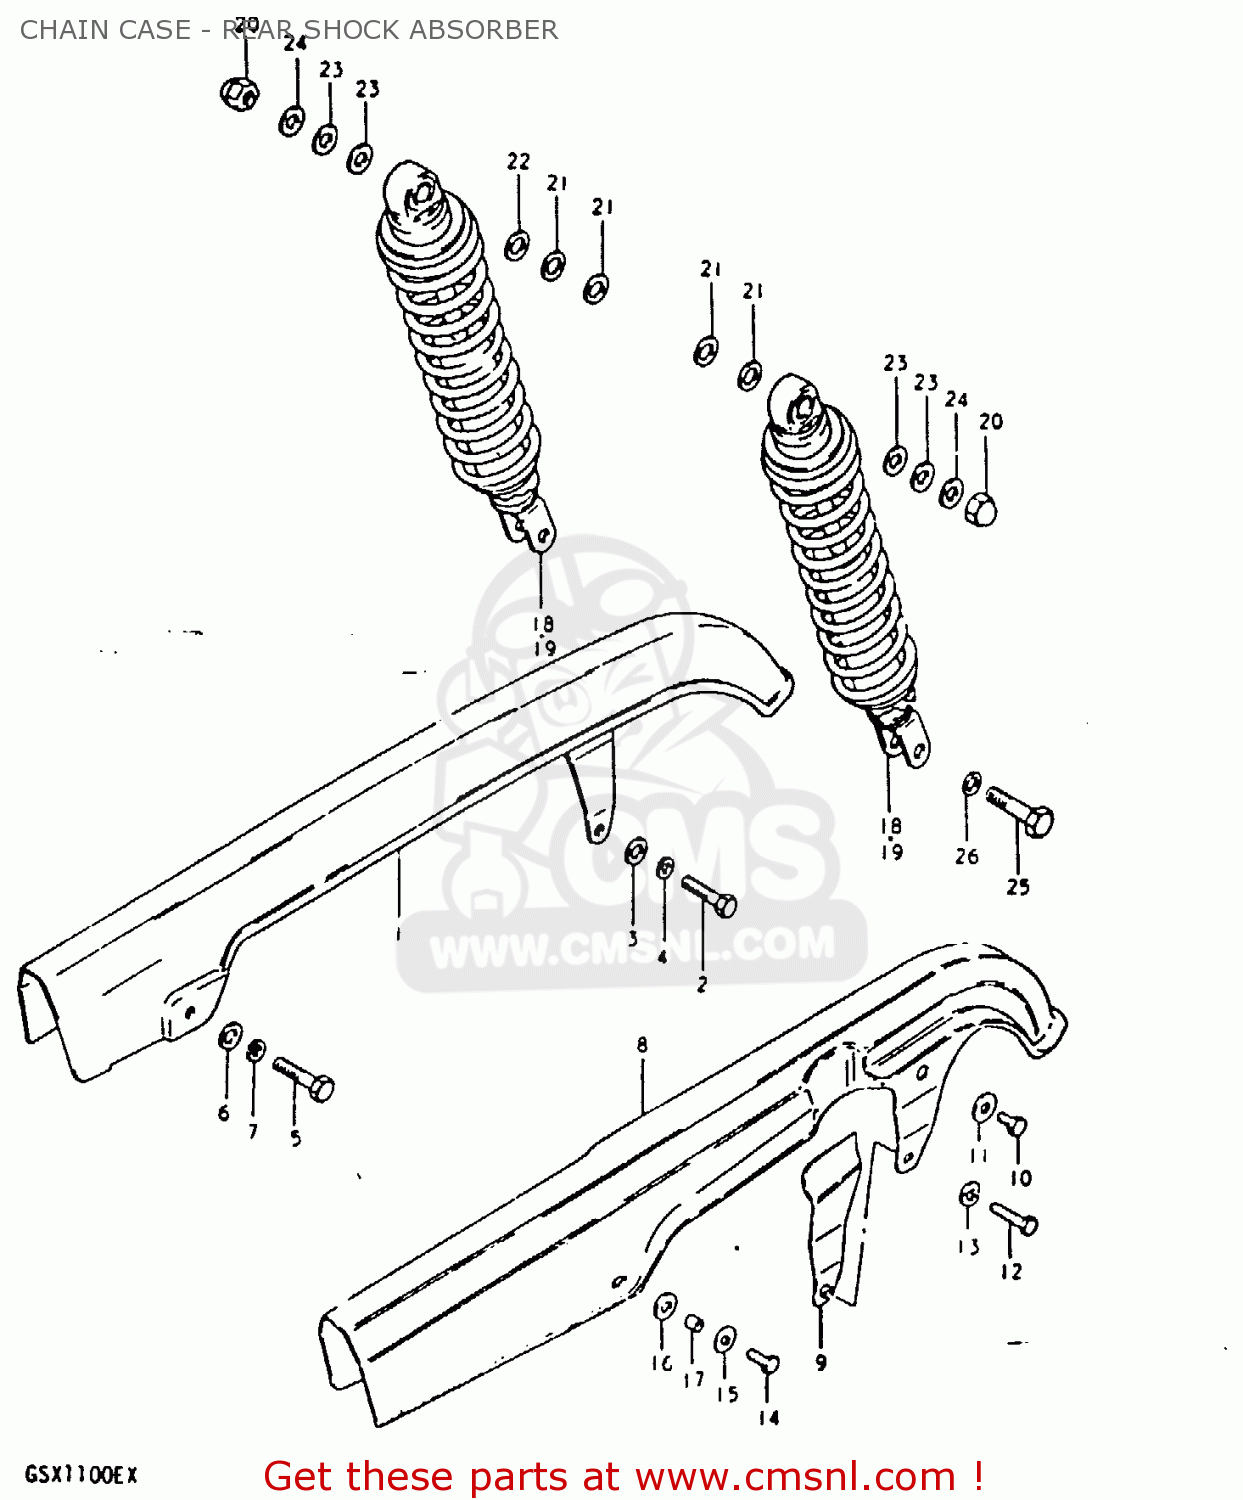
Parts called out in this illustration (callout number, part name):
1	CHAIN CASE
2	BOLT
3	WASHER
4	LOCK WASHER
5	BOLT
6	WASHER
7	LOCK WASHER
8	CASE,CHAIN
9	REINFORCEMENT,CHAIN CASE
10	BOLT(6X8)
11	WASHER
12	BOLT
13	LOCK WASHER
14	BOLT
15	WASHER(6.5X18X1)
16	CUSHION
17	SPACER (6.1X8X5.2)
18	SHOCK ABSORBER, REAR
19	SHOCK ABSORBER, REAR
20	NUT, LOWER LH
21	WASHER
22	WASHER (12.5X24X3.2)
23	WASHER
24	WASHER(10.5X24X3.2)
25	BOLT(10X36)
26	WASHER
